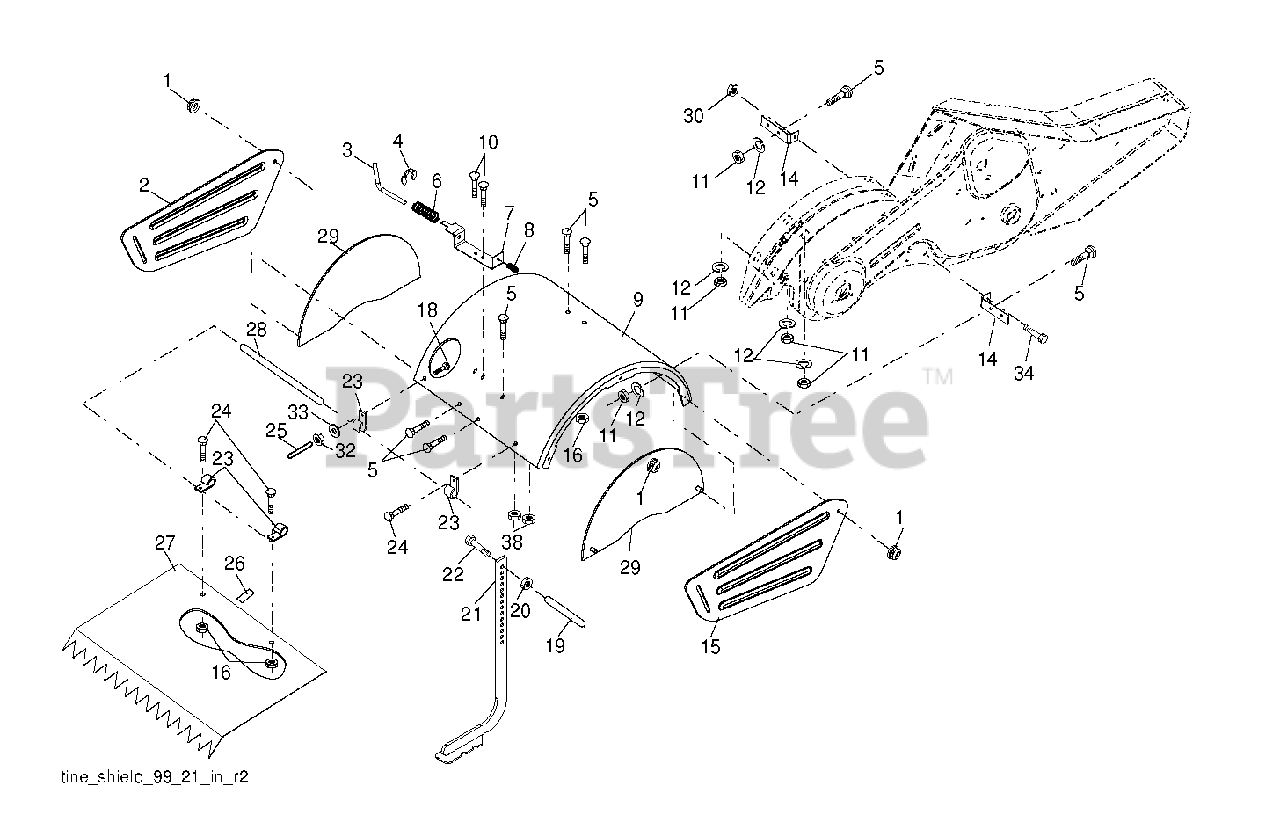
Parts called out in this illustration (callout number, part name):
1	NUT LOCK HEX FLANGE 5/16-18
2	SHIELD.SIDE.OUTER.LH.ORANGE
3	STAKE PIN TI
4	RING, KLIP
5	BOLT, RDHD SQNK 5/16-18 X 3/4
7	BRACKET.LATCH.STAKE.3.20.BLACK
8	SPRING CRT
9	SHIELD.TINE.TILLER.ORANGE
12	LOCKWASHER
14	BRACKET.TINE.SHIELD.TILLER
15	SHIELD.SIDE.OUTER.RH.ORANGE
16	NUT T
20	NUT.HEX.3/8-16UNC
21	STAKE.ASM.DEPTH
22	BOLT.375-16
25	VINYL CAP TI
26	PAD IDLER TI
27	SHIELD.PNT.LEVELING.ORANGE.668
28	PIN, HINGE
29	SHIELD.ASM.PNT.SIDE.ORANGE.668
30	LOCKNUT-FLANGE 5/16-18
32	NUT
33	LOCKWASHER
38	NUT
